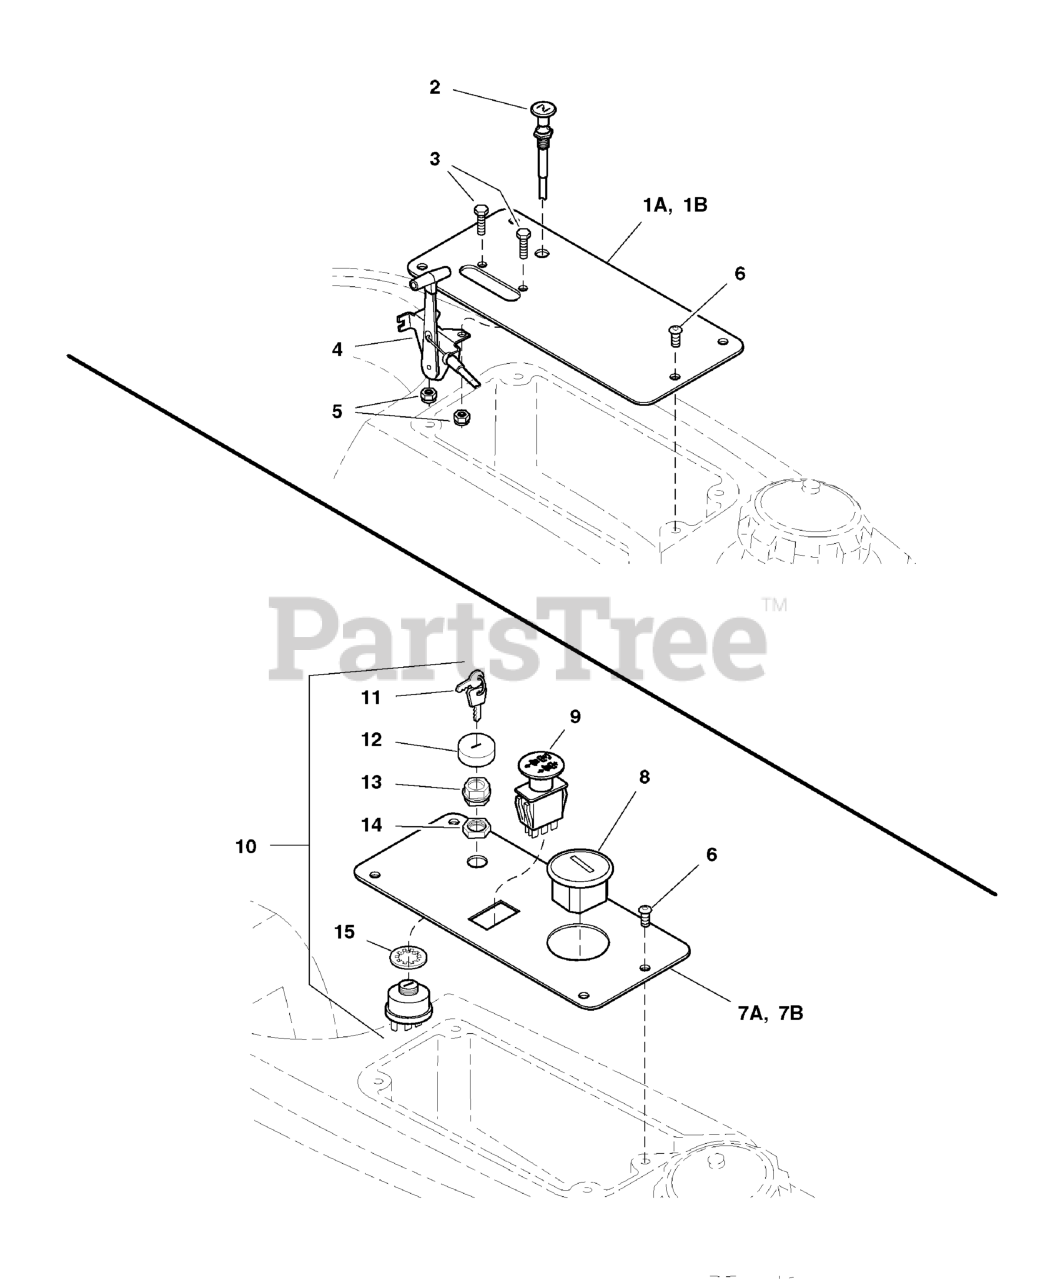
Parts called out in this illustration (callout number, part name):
1A	PANEL, Control-RH
1B	PANEL, Control-RH
2	CABLE, Choke Control, 47"
3	BOLT, 1/4-20 x 3/4
4	CABLE, Throttle, 45"
5	NUT, 1/4-20 HEX SERR. FLANGE
6	SCREW, Allen Head, 1/4-20 x 1/2
7A	PANEL, Control-LH
7B	PANEL, Control-LH
8	HOUR METER
9	SWITCH, BLADE ENGAGEMENT
10	SWITCH, IGNITION, 6 POST
11	KEY, IGNITION MOLDED SET
12	COVER, PLASTIC, SNAP ON
13	PLASTIC NUT
14	STEEL NUT
15	WASHER
